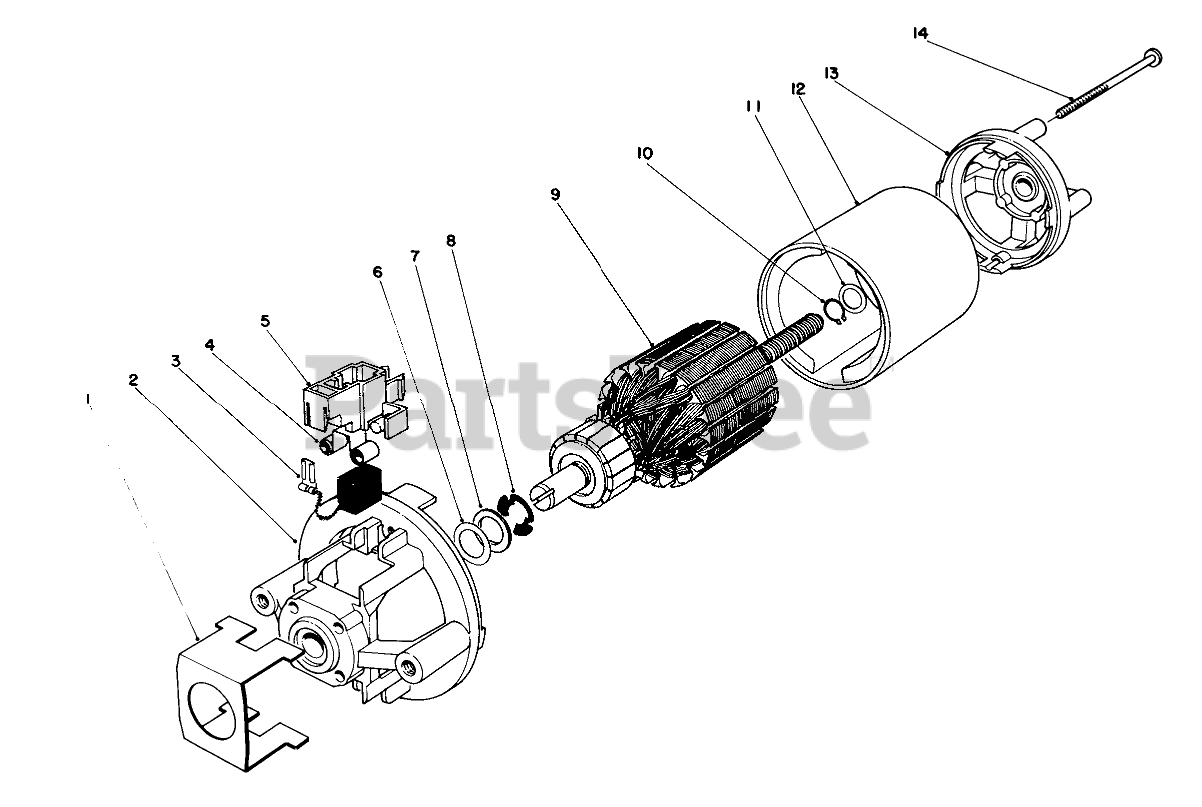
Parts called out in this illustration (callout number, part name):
3	Brush
4	Spring Brush
5	Brush Holder
10	Retaining Ring
